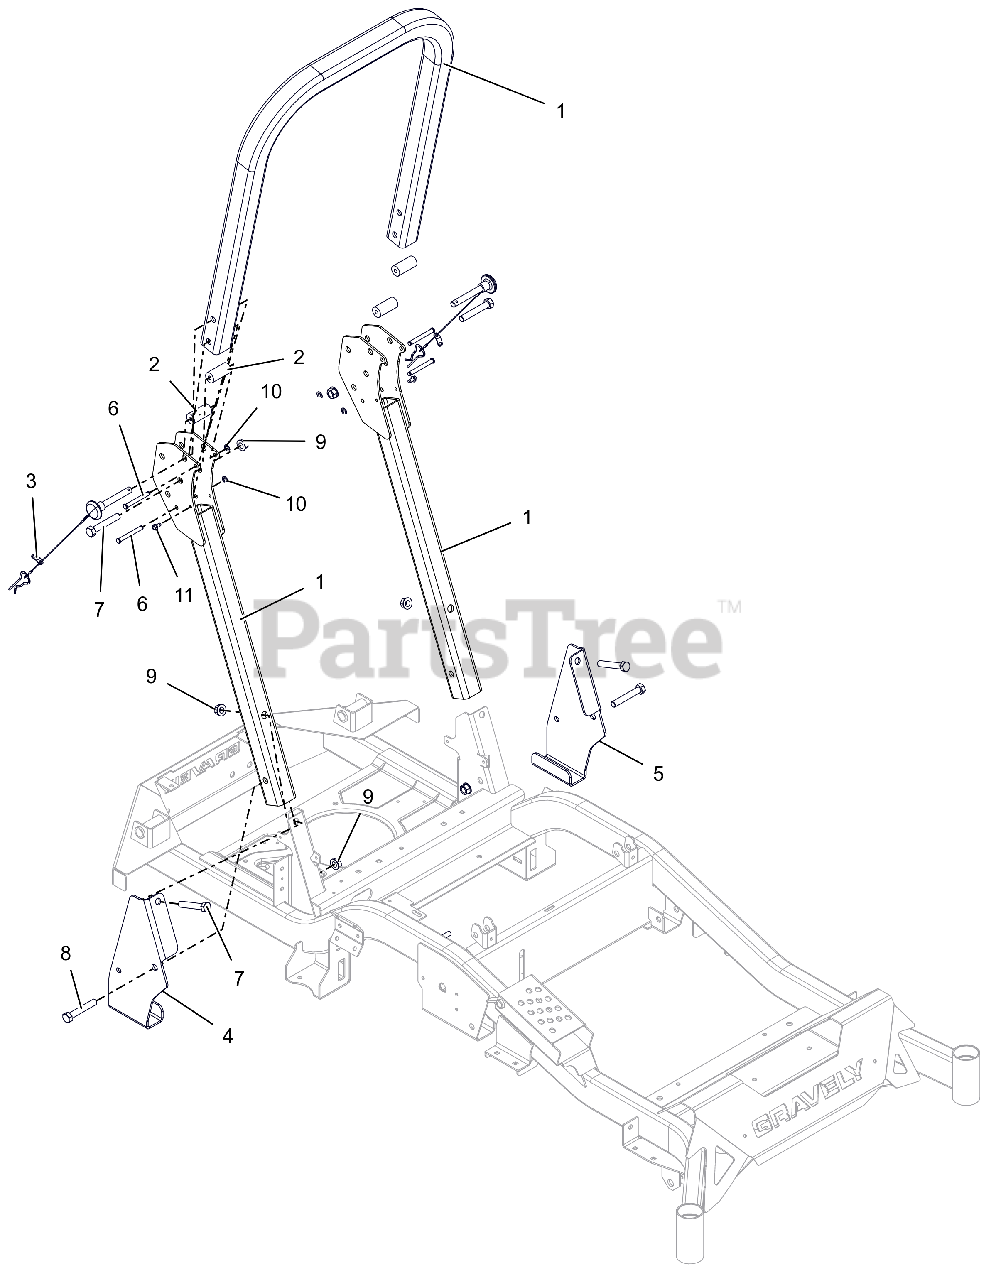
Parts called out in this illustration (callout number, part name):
1	ROPS,PROTURN Z REPLACEMENT-TALL
2	BUMPER, ROPS ANTI-VIBRATION
3	PIN, ROPS W/LANYARD
4	BRKT, ROPS SUPPORT - RH
5	BRKT, ROPS SUPPORT -LH
6	PIN, 5/16 X 2-9/16 WITH GROOVE
7	BLT, HEX .50-13X3.00 G5 ZCC
8	BLT, HEX .50-13X3.00 G5 ZCC
9	NUT-LK-CTR-FLG .500-13 GG ZCC
10	RING, RETAINING-E .312 X .025
11	SCR-TAP .25-20X.50 HWH ZCC
